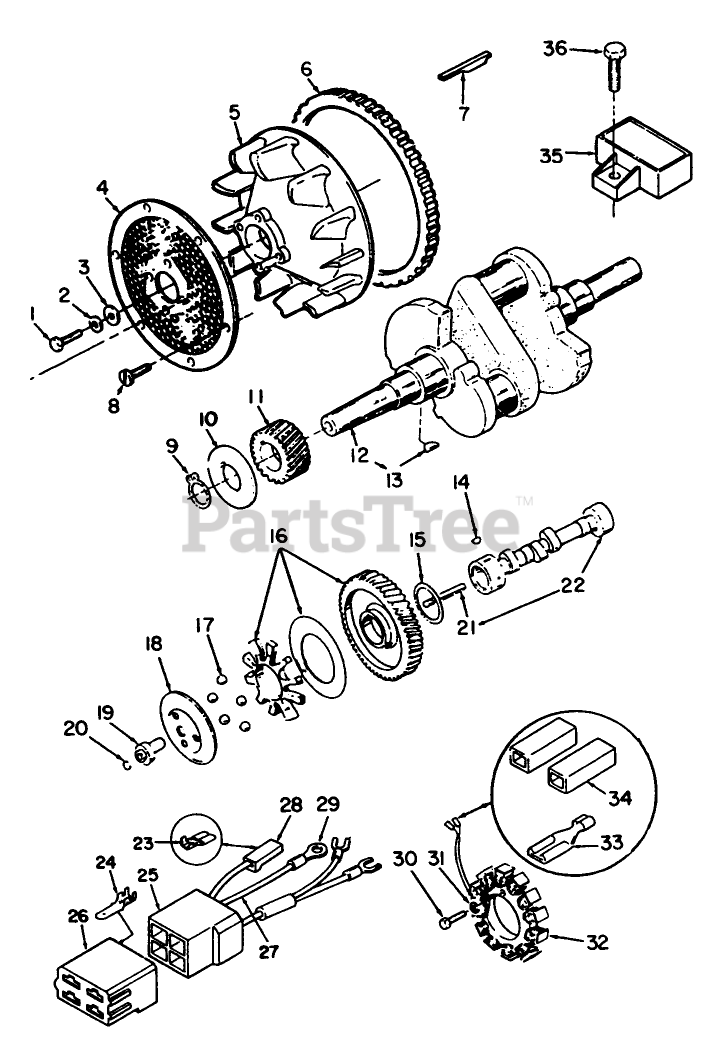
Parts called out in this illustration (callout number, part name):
1	SCREW
2	WASHER-LOCK
3	WASHER-FLAT
4	AIR INLET SCREEN
5	Flywheel (Incl. Ref. #6)
7	KEY-FLYWHEEL
8	LOCK SCREW
10	WASHER
12	Crankshaft (Incl. Ref. #13)
15	WASHER-THRUST
16	GEAR ASM
17	BEARING
18	CUP-GOVERNOR
19	HUB-GOVERNOR CUP
21	PIN-CENTER
22	Camshaft (Incl. Ref. #21)
23	RECEPTACLE TERMINAL
24	TAB TERMINAL
25	RECEPTACLE HOUSING
26	TAB HOUSING
27	ENGINE WIRING HARNESS
28	RECEPTACLE HOUSING
29	RING TERMINAL
30	SCREW
31	WASHER-LOCK
32	Stator
33	TERMINAL
34	Body-Terminal
35	Regulator
36	SCREW-HWH
